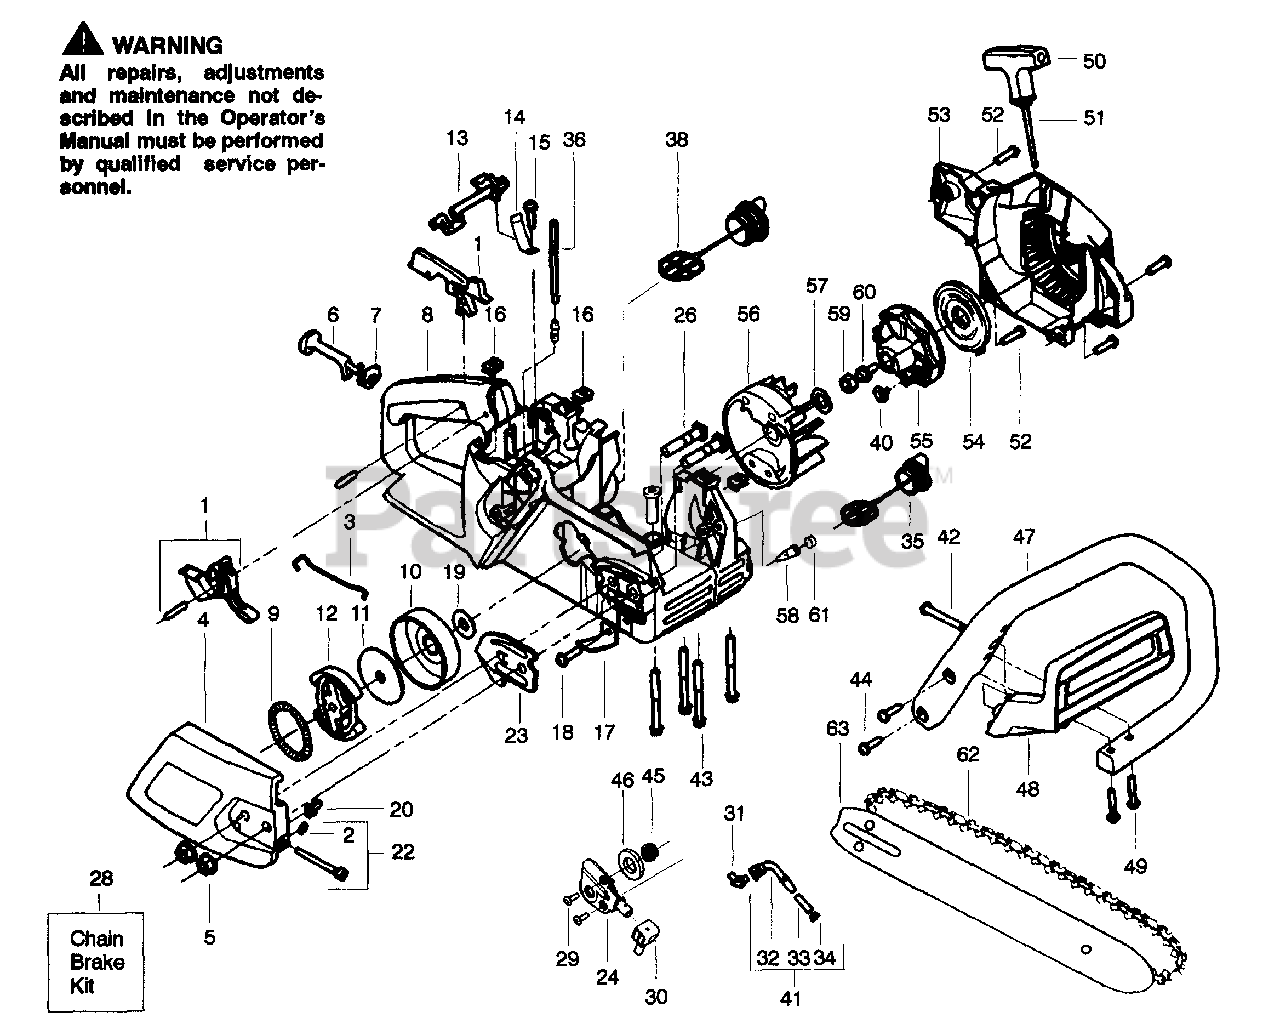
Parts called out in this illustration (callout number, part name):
1	Trigger & Lockout Kit
2	Retainer-Bar Adjust
3	Wire - Throttle
4	Clutch Cover
5	Nut - Bar Mounting
6	Choke Lever
7	Grommet-Choke Knob
8	Chassis Ass'y. Kit
9	Clutch Spring
10	Clutch Drum Ass'y - w/Brg.
11	Washer - Clutch
12	Clutch Ass'y.
13	Switch Lever
14	Switch Spring
16	Nut-Speed
17	Chain Catcher
19	Washer - Thrust
20	Pin - Bar Adjusting
22	Bar Adjusting Screw Kit
23	Bar Mounting Plate
24	Oil Pump Kit
28	Chain Brake Kit
30	Seal Block
31	Elbow-Oil Pickup
32	Pick-Up Oiler
33	Oil Filter
34	Plug- Oil Filter
35	Oil Cap Ass'y.
36	Fuel Line Kit (Large)
38	Fuel Cap Ass'y.
41	Oil-Pickup Ass'y.
45	Gear Worm Spring
46	Dust Seal
47	Front Handle
48	Handguard
50	Starter Handle
51	Rope Kit
53	Fan Housing
54	Starter Spring
55	Starter Pulley
56	Flywheel Ass'y.
57	Washer-Flywheel
58	Check Valve
59	Nut-Flywheel
61	Plug - Bronze Vent
62	Chain-18"
